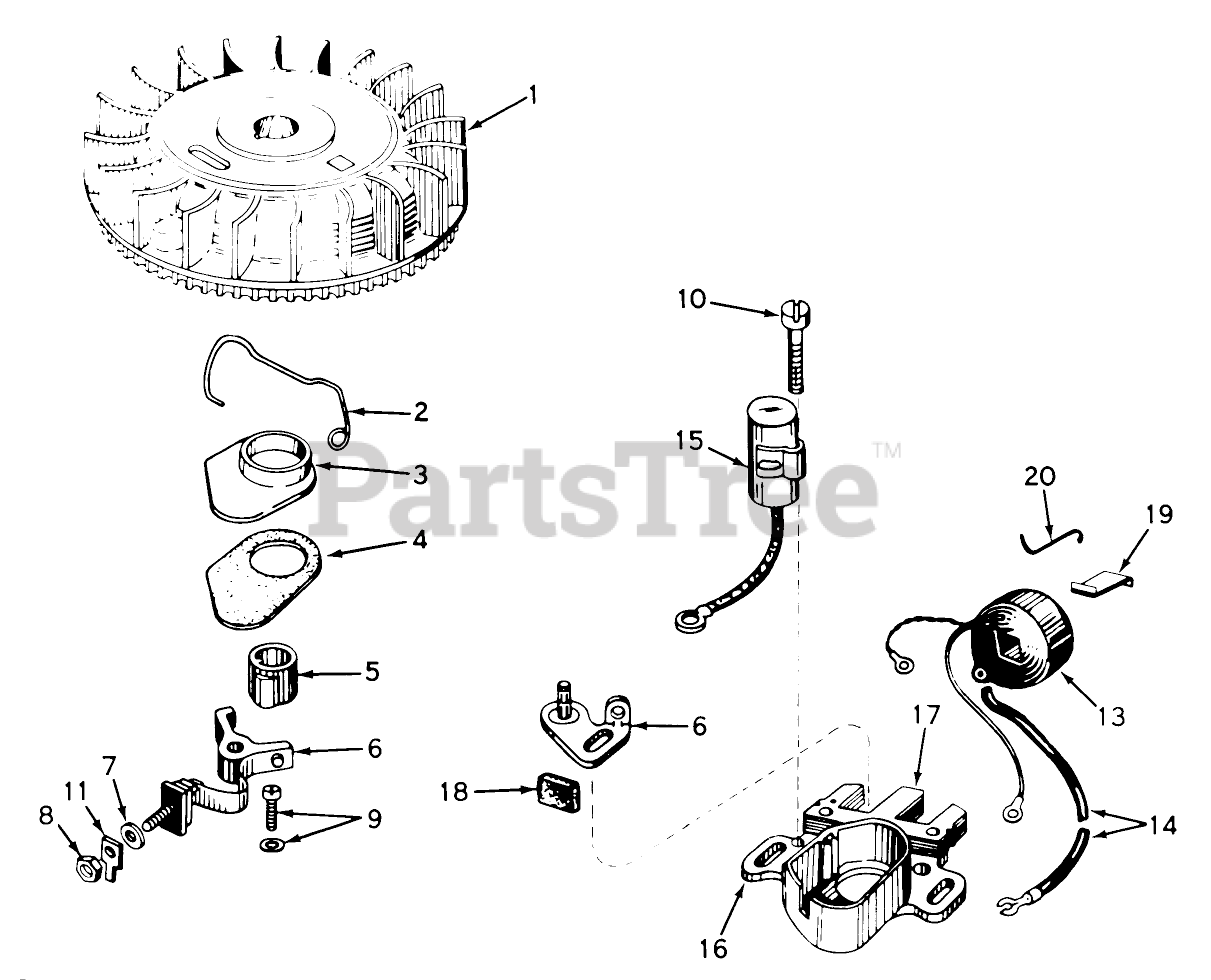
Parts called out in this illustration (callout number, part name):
1	FIywheel
2	Spring Breaker Box
3	Cover, Dust
4	Gasket Dust Cover
5	Cam, Breaker
6	Breaker Assy.
7	Washer
8	DECAL
9	Breaker Screw
10	Condenser Screw
11	Terminal
13	Coil Assy., (Inc. Ref. Nos. 12, 13 18)
14	Wire, Lead
15	Condenser
16	Core Plate
17	Stator Assy., (Incl. Nos. 2, 3, 5 thru 14 16 thru 19)
18	Felt,Cam Wiper
19	Spring Coil Wedge
20	Clip, Coil
